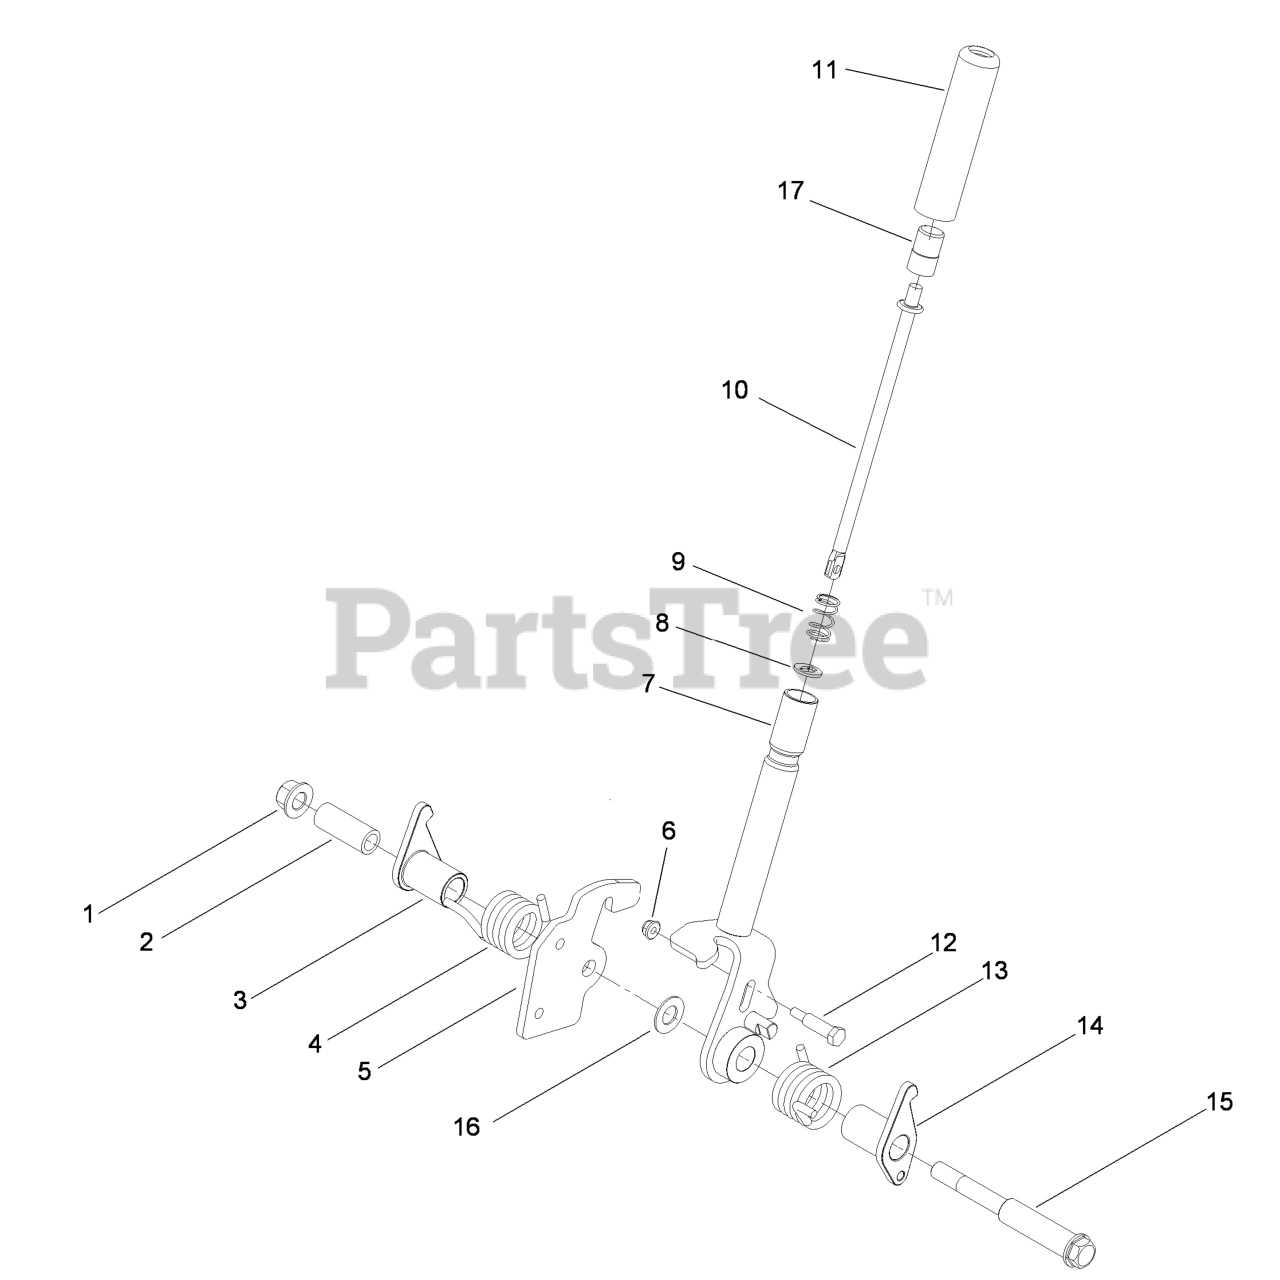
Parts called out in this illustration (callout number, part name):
1	Nut-Lock 1/2-13
3	ARM-BRAKE, LH
4	SPRING-TORSION, RH
5	PLATE-LATCH
7	BRAKE HANDLE ASM
8	WASHER-SPECIAL
9	SPRING-COMPRESSION
10	ROD-RELEASE, BRAKE
12	BOLT-SHOULDER
13	SPRING-TORSION, LH
14	ARM-BRAKE, RH
15	BOLT-SHOULDER
16	WASHER-FLAT
